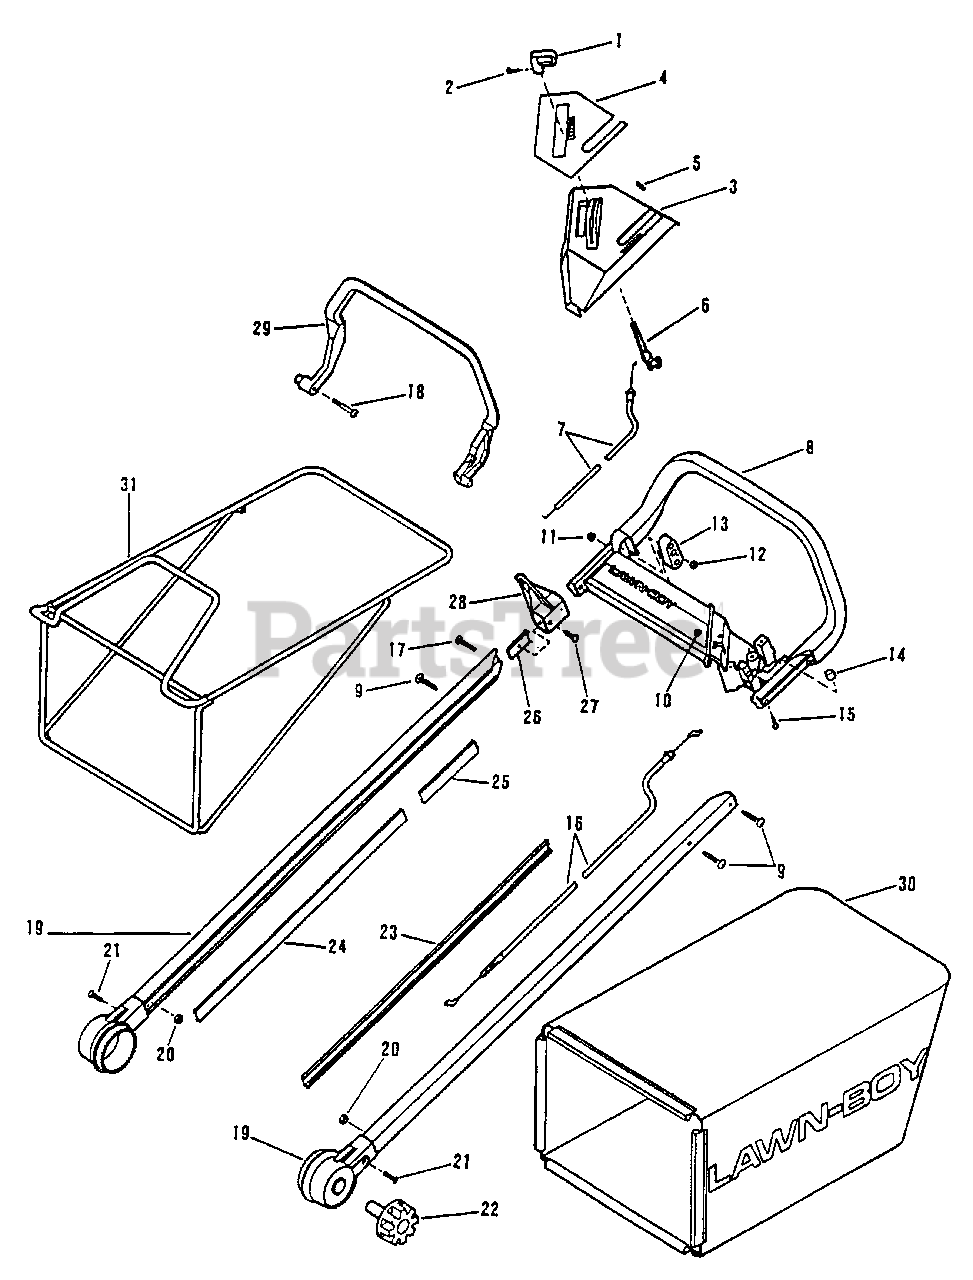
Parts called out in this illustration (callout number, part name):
1	Throttle Knob Assy (Inc. 2)
2	Set Screw
3	Upper Cover Assy (Inc. 4)
4	Plate
5	Plug
6	Throttle Lever
7	Throttle Cable Assy
8	Handle & Decal Assy (Inc. 9-10)
9	Thread Forming Screw
10	Decal-Lawn-Boy
11	Locknut
12	Locknut
13	Bail Block
14	Bumper
15	Screw-Cover to Handle
16	Engine Brake Cable Assy
17	Screw-Extrusion & Block to Hdl
18	Screw-Bail Pivot
19	Handle Shaft Assy (Inc. 20-21)
20	Nut
21	Screw
22	Handle Adjustment Knob
23	Handle Insert-Cable Side
24	Handle Insert-Below Guide
25	Handle Insert-Above Guide
26	Nut Plate
27	Screw-Rope Guide to Handle
28	Rope Guide
29	Engine Brake Bail
31	Frame
